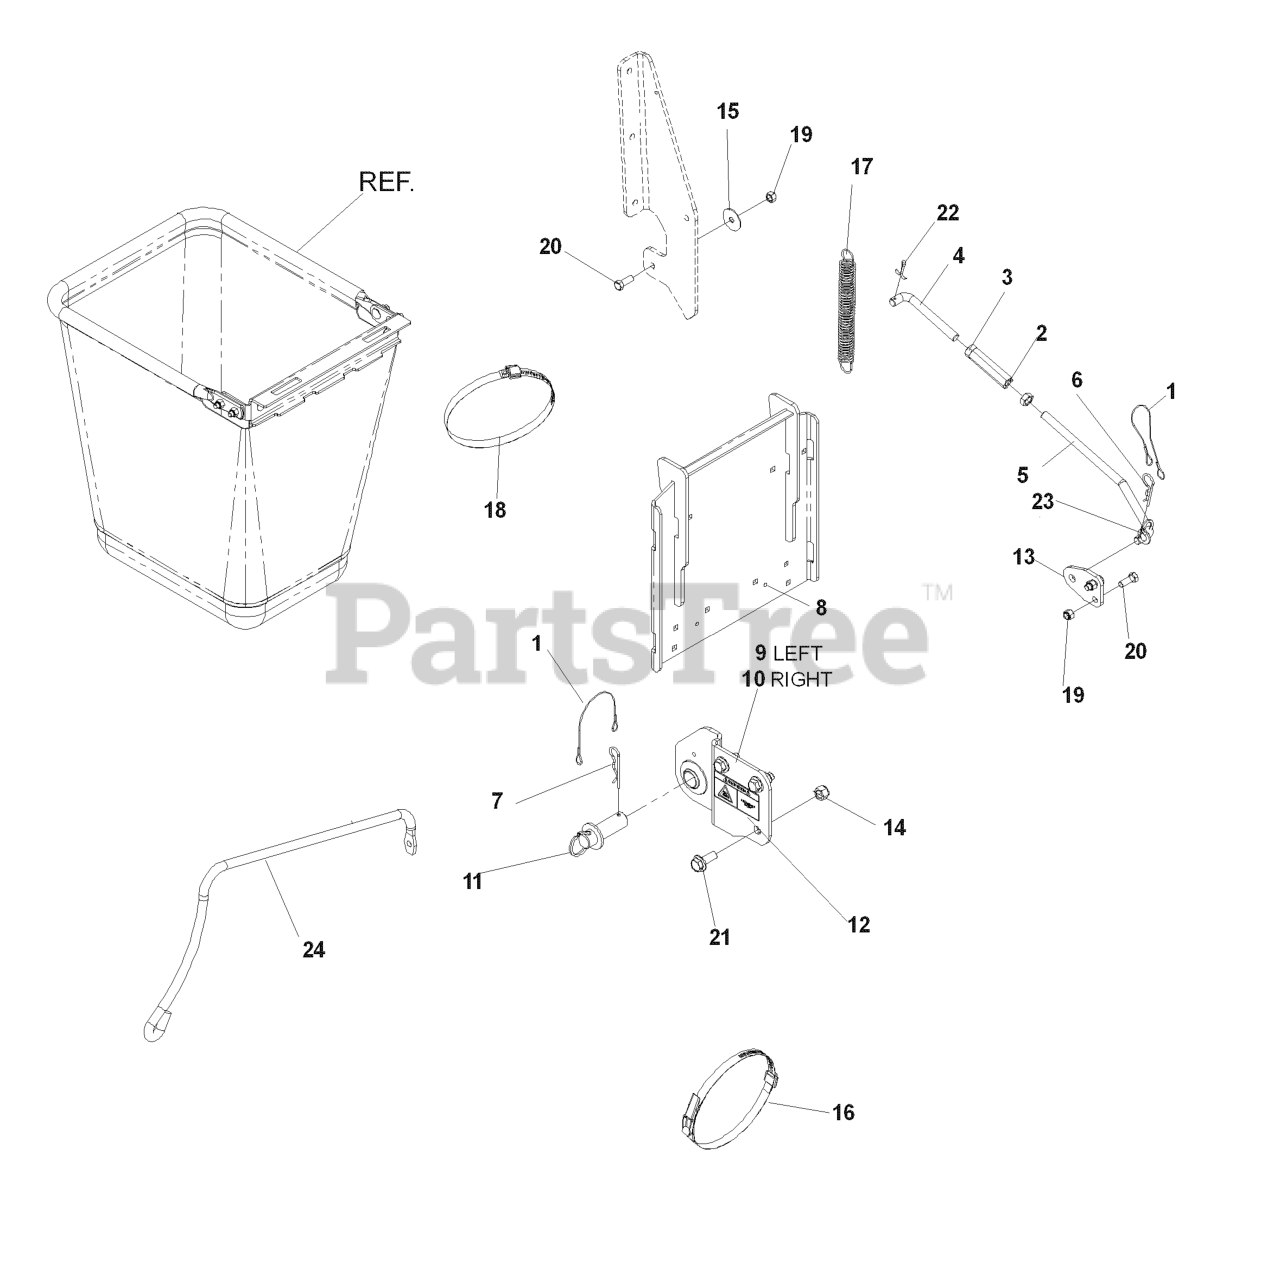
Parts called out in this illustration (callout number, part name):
2	NUT 1/2-20 HEX JAM ZD
3	TURNBUCKLE, 1/2
4	SUPPORT LINKAGE, LH
5	SUPPORT LINKAGE, MID
6	HAIRPIN #4
8	REAR GUARD WELDMENT
9	HITCH BRACKET WLD
10	HITCH BRACKET W/ DECAL MID
12	DECAL, HOT SURFACE
13	SUPPORT BRACKET
14	NUT 1/2-13 HEX NYLOC ZD
15	WASHER, FRICTION
16	OVER CTR BAND
18	HOSE CLAMP 4-1/8 TO 7"
19	NUT 3/8-16 NYLOC
20	HCS 3/8C X 1 1/2
21	HCS 1/2C X 1 1/4 SERRATED HEAD
22	COTTER PIN
24	HOSE SUPPORT
